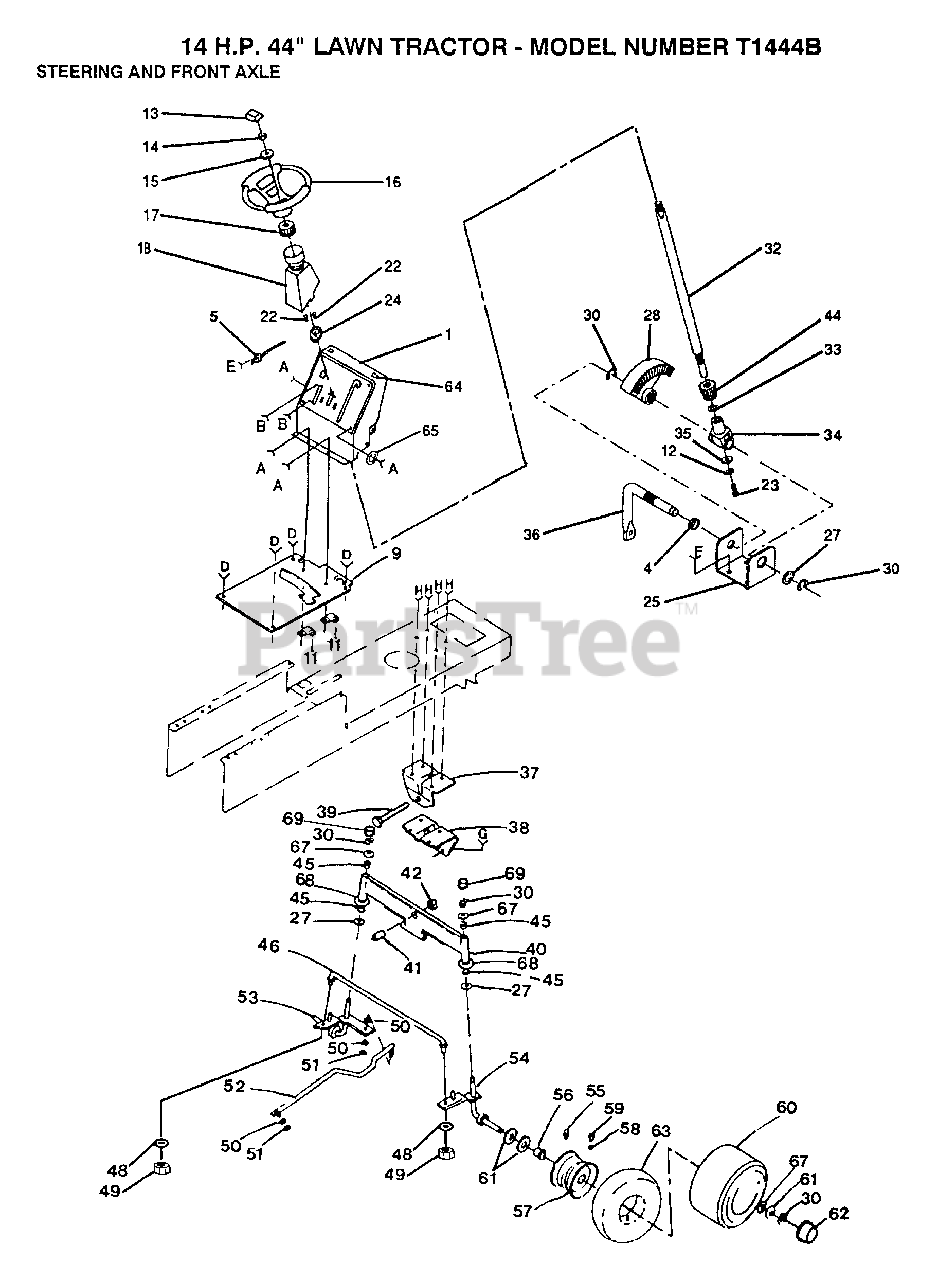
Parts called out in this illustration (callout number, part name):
4	NYLINER T
11	CLIP T
12	LOCKWASHER
13	INSERT-WHEEL LT
15	WASHER
17	ADAPTER LT
18	"TUBE, STR SHAFT"
23	"SCREW,SPECIAL"
24	"BUSHING,STEERING"
25	"BRKT,STEERING"
27	WASHER .T
30	RING
33	THRUST WASHER
34	SUPPORT.SHAFT
37	SUPPORT-SADDL T
38	SUPPORT.SADDLE.FT
39	BOLT LT
41	BEARING
42	"NUT-LOC,FLANGE LT"
44	"GEAR,PINION"
45	COL. SRTG. BEAR.
46	ROD TIE
48	LOCKWASHER
49	NUT.LOCK.5/16-24
50	LOCKWASHER
53	SPINDLE-LH LT
55	FITTING LT
56	"FLANGE, BEARING"
58	VALVE CAP
59	VALVE STEM LT
61	WASHER
62	HUB CAP
63	TUBE.5.3/4.5/6
65	LOCKWASHER.5/16.E
67	WASHER
68	WASHER
69	CAP
